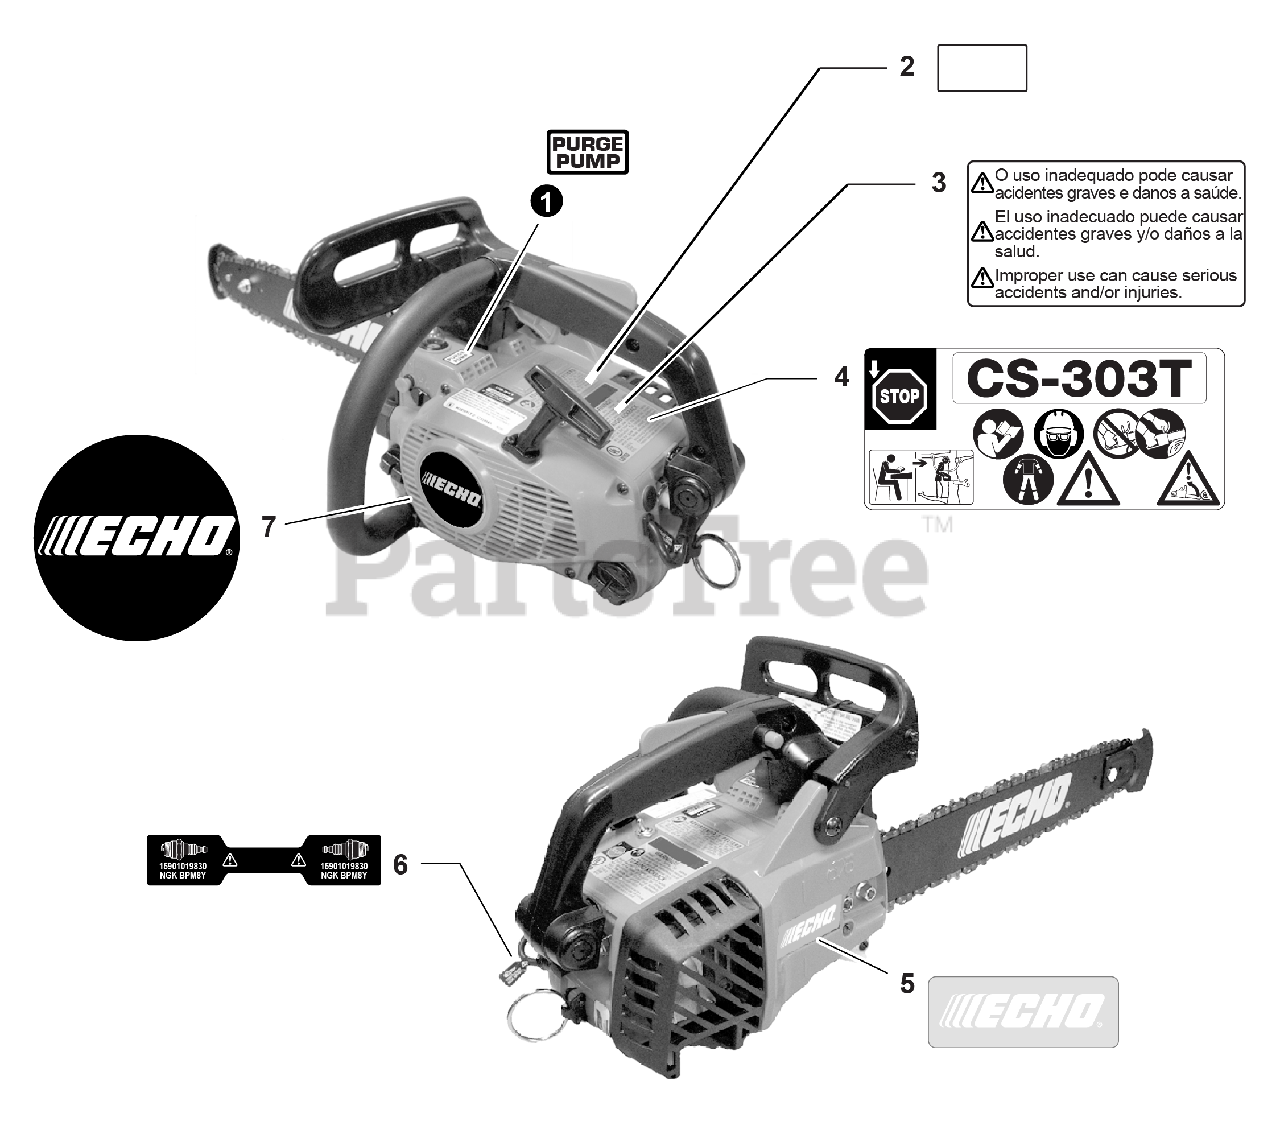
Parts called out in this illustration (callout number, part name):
1	LABEL, PURGE PUMP
2	LABEL - JAPAN TECHNOLOGY
3	LABEL, CAUTION
4	LABEL - MODEL CS-303T
5	LABEL, ECHO
6	LABEL, SPARK PLUG - BPM8Y
7	LABEL, ECHO
